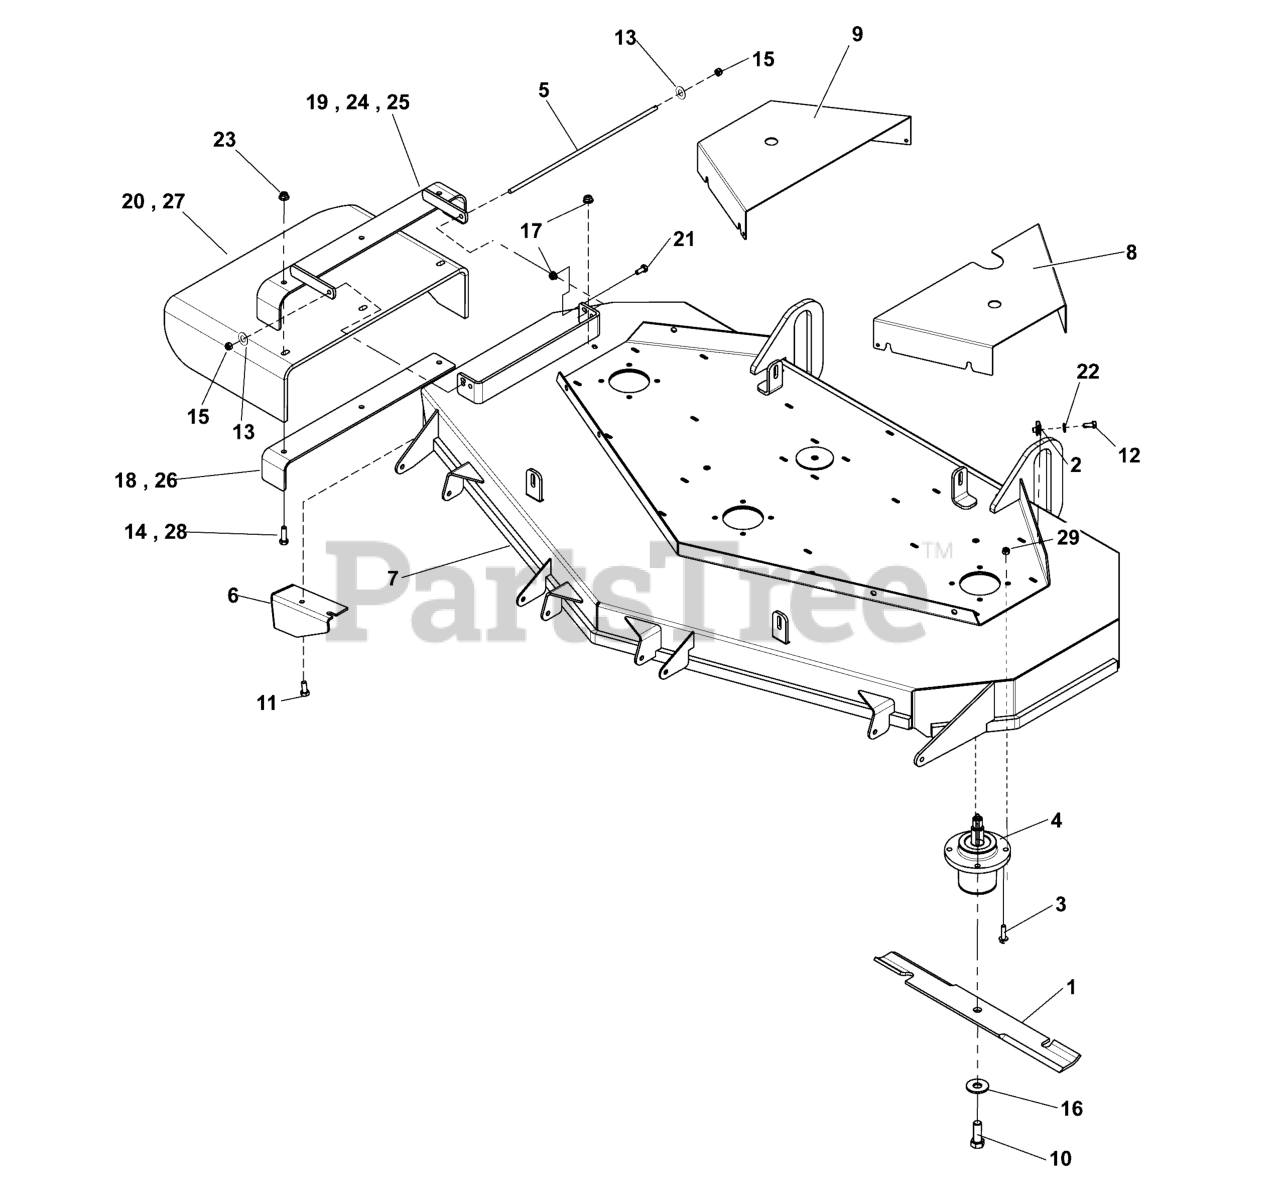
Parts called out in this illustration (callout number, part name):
1	BLADE SET, 61 DECK (3)
1	BLADE SET, 61 DECK (SET OF 3 BLADES)
2	BODY CLIP, 5/16-18-7GA MATERIAL
3	BOLT, 3/8-16 X 1-1/4, FLANGE, GD 5, CZ
4	ASSM, SPINDLE, LOW PROFILE
5	ROD MOUNT, CHUTE 61"
6	PLATE, DEFLECOR - BLK
7	DECK SHELL W/DECALS, 61" - TWR
8	GUARD, DECK, 61", LH, TWR - RED
9	GUARD, DECK, 61", RH, TWR - RED
10	BOLT, 5/8-11 X 1-3/4 GD8
11	BOLT, 5/16-18 X 3/4, CARRIAGE
12	BOLT, 5/16-18 X 1" GD5 YZ
13	WASHER, 5/16 GD.9 FLAT
14	BOLT, 3/8-16 X 1-1/2" GD5 CZ
15	NUT, 5/16-24 HEX NYLON LOCK
16	WASHER, 5/8" GRADE 8
17	NUT, 5/16-18 HEX NYLOCK FLANGE
18	SUPPORT, DISCHARGE CHUTE - BLK
19	WELD, FRAME, CHUTE, 61 - RED
20	CHUTE, DISCHARGE, RUBBER, 61/72, BENT
21	BOLT, 5/16-18 X 3/4 GD5
22	WASHER, 5/16" SAE
23	NUT, 3/8-16 HEX NYLOCK FLANGE
24	WELD, FRAME, CHUTE, 61" - BLK
26	SUPPORT, DISCHARGE CHUTE - BLK
27	CHUTE, RUBBER DISCHARGE (5104442)
28	BOLT, 3/8-16 X 1-1/2, CARRIAGE, GD5, CZ
29	NUT, 3/8 - 16 HEX NYLOCK FLANGE
